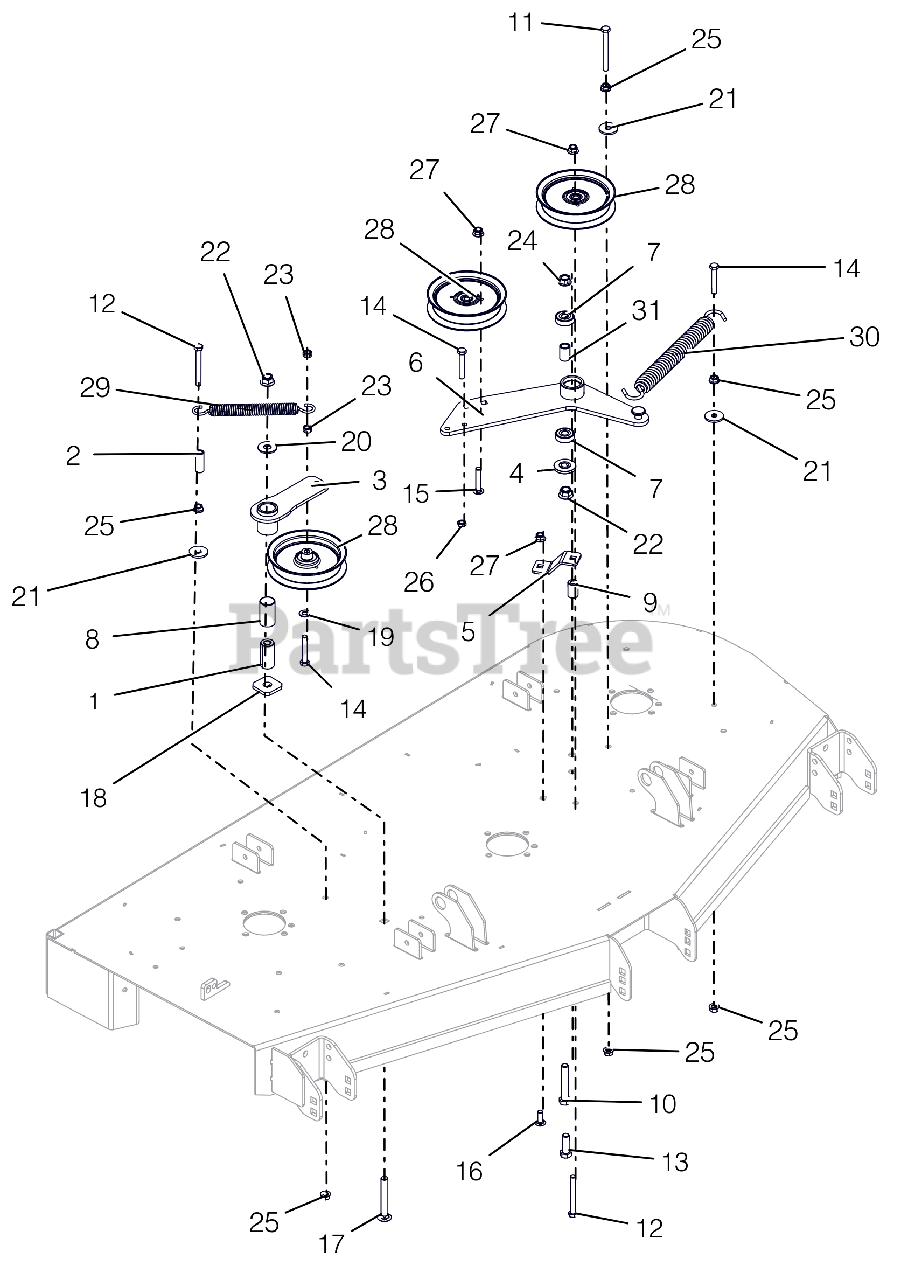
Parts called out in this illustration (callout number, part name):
1	BSHG, SPCR .502X.997X2.03 PM
2	SPACER, .375IDX.625ODX1.66 PM
3	WMT, IDLER ARM - BLACK
4	SPACER, IDLER ARM
5	PTO FIXED IDLER MTG BRKT-ORG
6	DECK PTO IDLER ARM WLDMT - BLK
7	BRG-BALL .500X1.38X.437
8	BSHG, 1.00X1.125X1.937
9	BUSHING, SLV .380X.750X1.190
10	@BLT-HEX .50-13X3.00 GR5 YWZC
11	@BLT-HEX .38-16X3.50 GR5 YWZC
12	@BLT-HEX .38-16X3.25 GR5 YWZC
13	@BLT-HEX .50-13X1.50 GR5 YWZC
14	@BLT-HEX .38-16X2.25 GR5 YWZC
15	BLT-RDHDSQNK .38-16X2.00 SHTYW
16	@BLT-RDHDSHSQNK.38-16X1.0 G5YZ
17	@BLT-RDHDSQNK .50-13X3.50 G5YZ
18	WSHR-FLT .640X1.75X.250
19	@WSHR-FL-STL.406X.812X.065 YWZ
20	@WSHR-FL-STL.563X1.38X.109YWZC
21	WSHR-FL-STL .406X1.375X.135 YZ
22	@NUT-LK-NYL-FLG .50-13 YWZC
23	@NUT-LK-CTR .38-16 YWZC
24	NUT-LK-CTR-FLG .50-13 YWZC
25	@NUT-SPNLK-FLG .375-16 YWZC
26	NUT-HEX-JAM .375-16 YWZC
27	@NUT-LK-NYL-FLG .38-16 YWZC
28	IDLER, FLAT 5.00"
29	SPRING, EXTENSION
30	SPRING, EXTENSION
31	SPACER .510 X .75 X 1.1485
